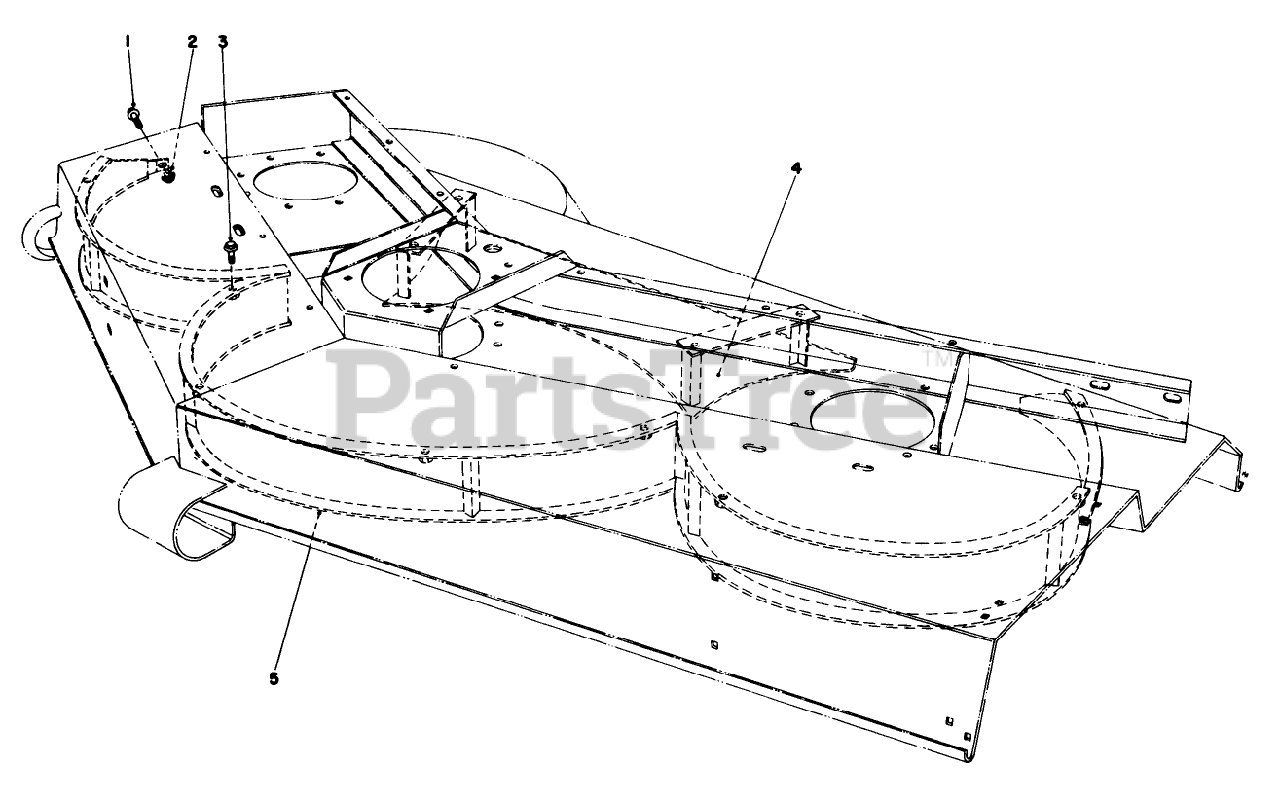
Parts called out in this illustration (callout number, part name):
1	SCREW-HHF
2	NUT-HF
3	SCREW-HHF
4	BTM REAR SHIELD WA R
5	Mulcher Screen
